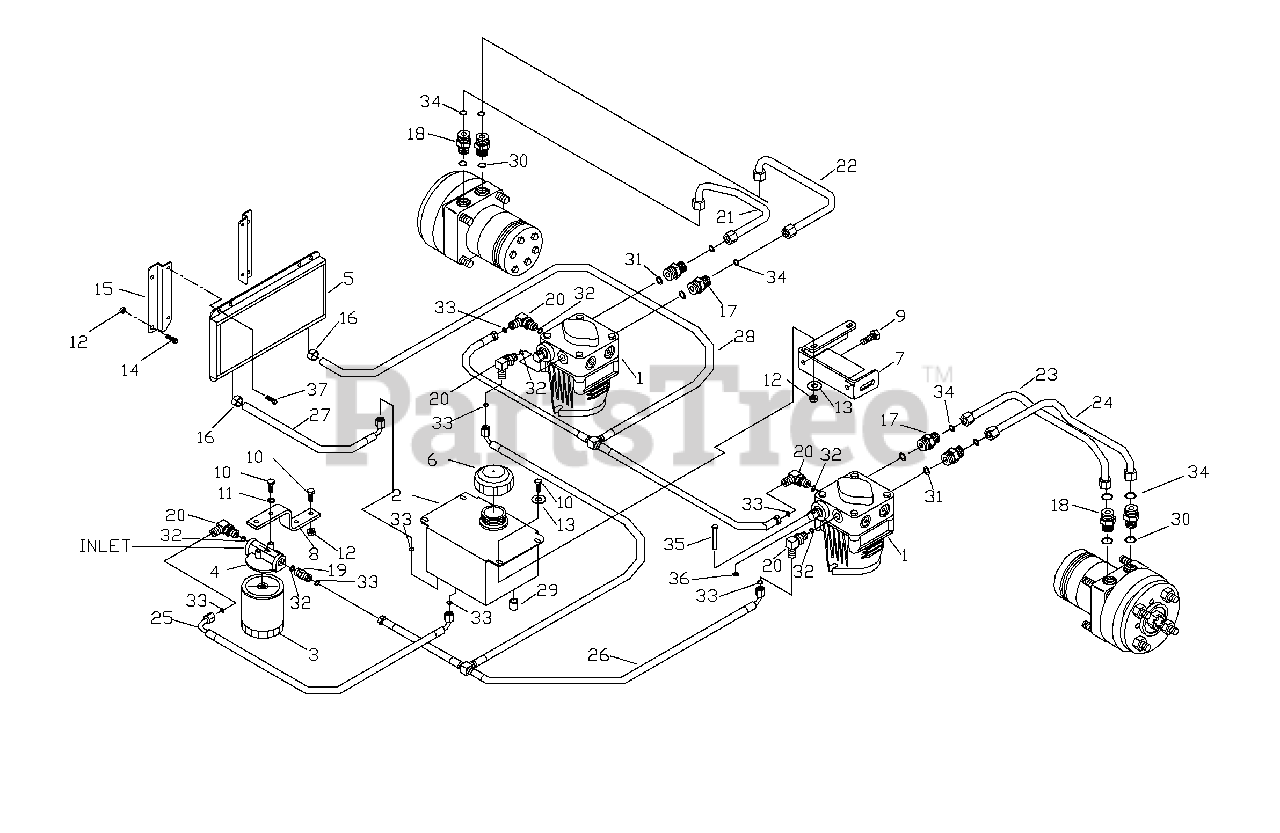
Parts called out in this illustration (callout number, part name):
1	PUMP
4	FILTER HEAD
7	TANK MOUNT LT.
7	TANK MOUNT RT.
8	FILTER BRACKET
9	HCS 5/16 X 3/4
10	HCS 1/4C X 3/4
11	1/4 LOCK WASHER
12	1/4 LOCK NUT
13	1/4 FLAT WASHER
14	HCS 1/4C X 2.0
15	COOLER BRACKET
16	HOSE CLAMP
18	STR. FITTING
21	R. OUTSIDE TUBE
22	R. INSIDE TUBE
23	L.INSIDE TUBE
24	L. OUTSIDE TUBE
30	3/4 "O" RING
31	1/2 "O" RING
32	3/8 "O" RING
33	3/8 "O" RING FLARE
34	3/8 "O" RING FLARE
35	CLEVIS PIN
37	HCS 1/4 SELF TAP
